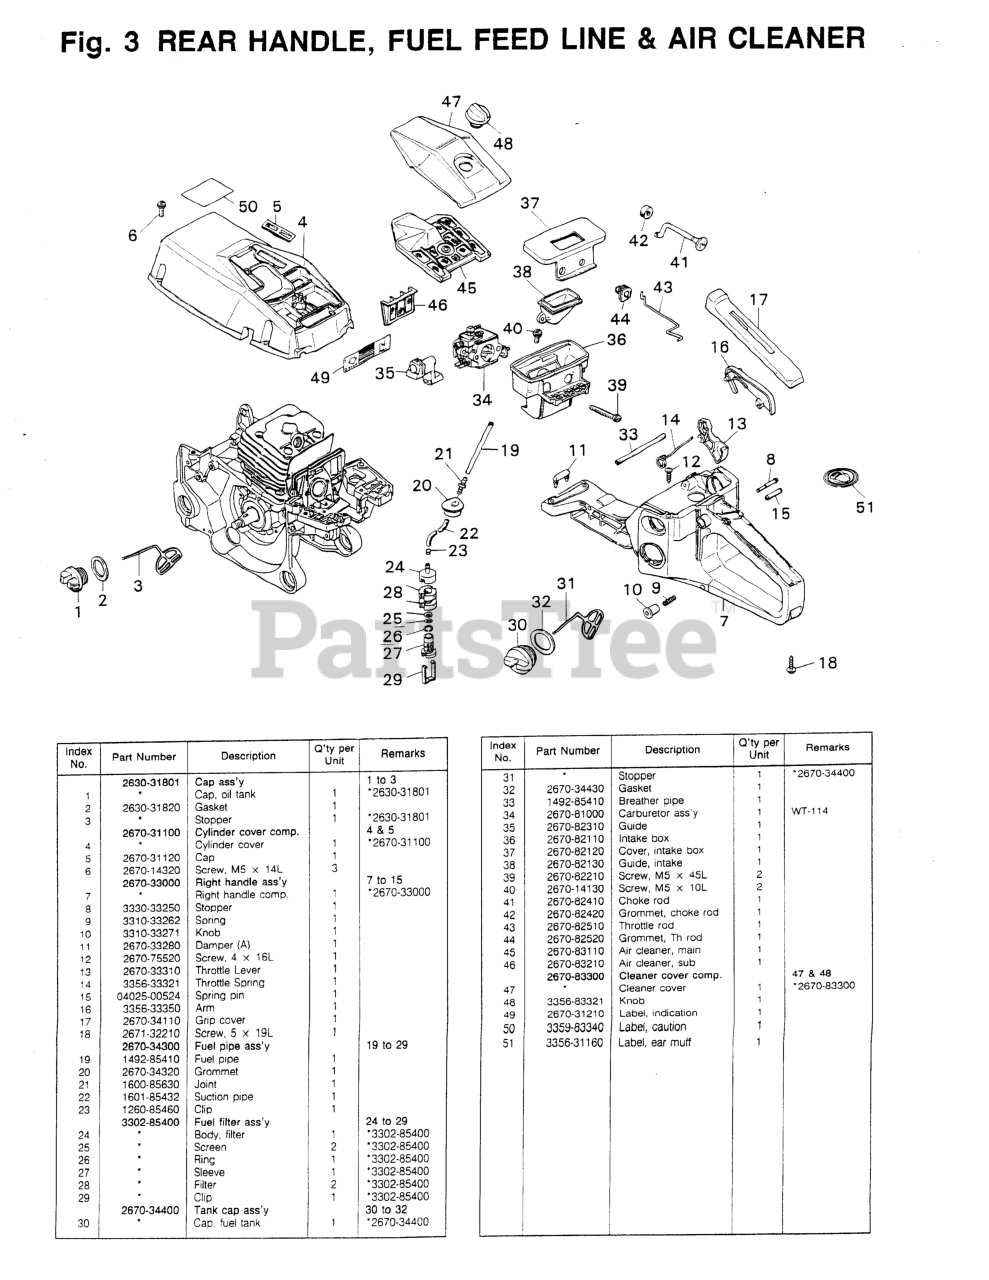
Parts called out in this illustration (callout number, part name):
2	GASKET
4	COVER COMP
6	SCREW (REPLACES 2616-24320)
7	RIGHT HANDLE ASSY
8	STOPPER
10	KNOB
14	SPRING
17	COVER, GRIP
18	SCREW (USE 848-825-1901)
19	PIPE (USE -85411)
22	PIPE, SUCTION
23	CLIP (REPLACES 2841-31280)
24	FILTER ASSY
25	FILTER ASSY
26	FILTER ASSY
27	FILTER ASSY
28	FILTER ASSY
29	FILTER ASSY
32	GASKET
33	PIPE (USE -85411)
38	GUIDE, INTAKE
39	SCREW
40	SCREW
43	ROD, THROTTLE
47	CLEANER COVER
49	LABEL (USE 2813-31210)
